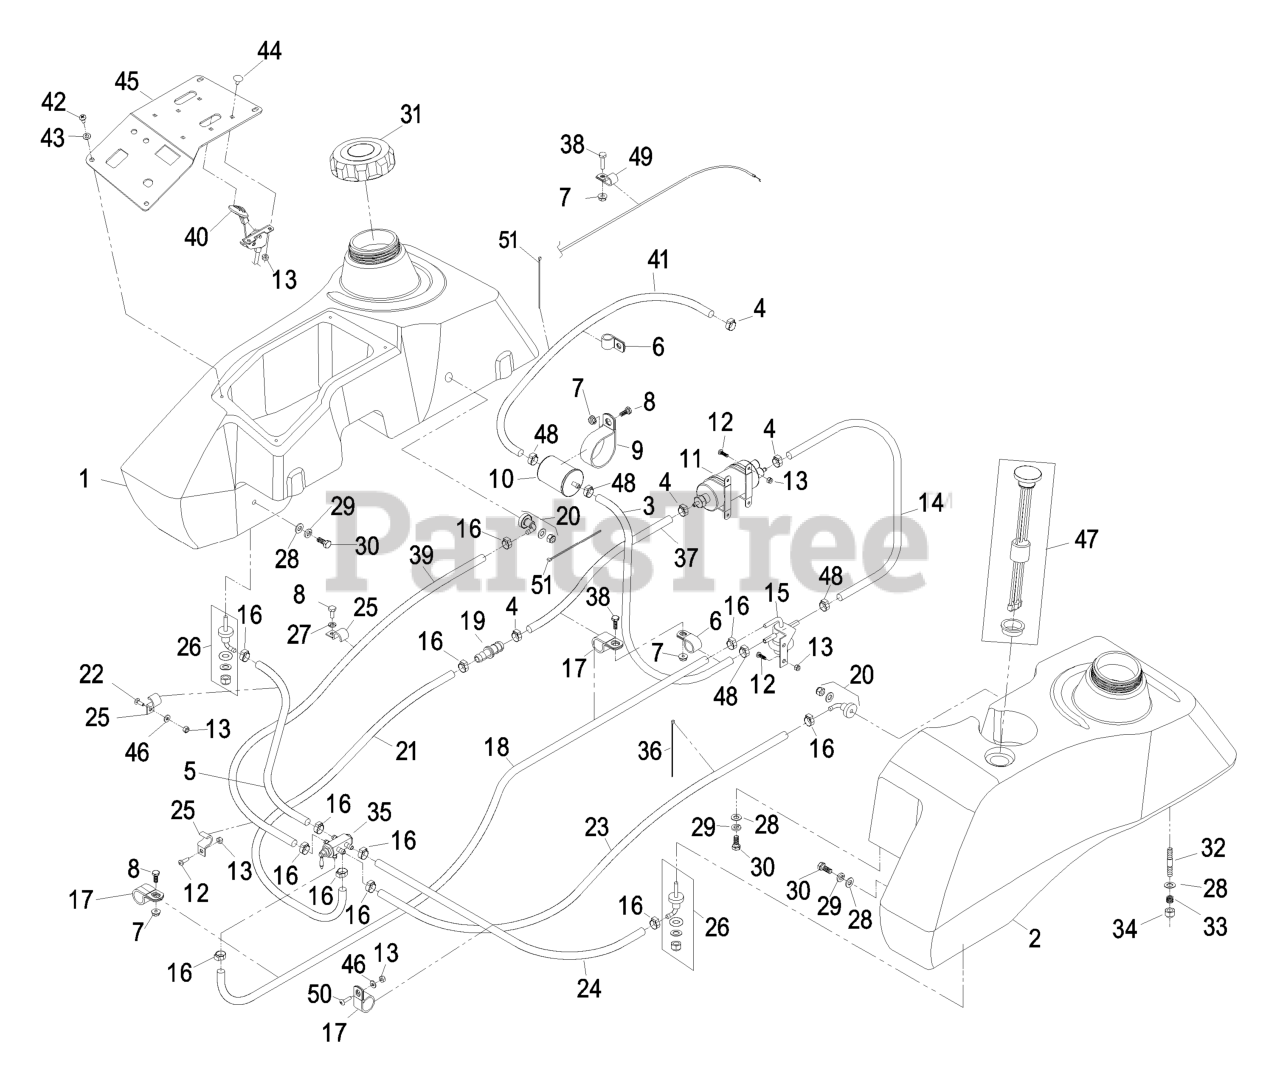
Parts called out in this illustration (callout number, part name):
3	Kit, Fuel Line W/Clamps
4	CLAMP-HOSE, FUEL
5	HOSE-FUEL
6	CLIP-LOOM
8	SCREW-HH
9	CLIP-LOOM
10	Kohler Part No. 24 050 03 Fuel Filter (Large)
11	Kohler Part No. 393 20 Fuel Pump
12	SCREW-PPH
13	NUT-LOCK, NI
14	KIT,FUEL LINE EFI PUMP-RE
15	Kohler Part No. 24 403 17 Fuel Regulator
16	CLAMP-HOSE, FUEL
17	CLIP-LOOM
18	HOSE-FUEL
19	CONNECTOR
20	FITTING-FUEL, BULKHEAD
21	HOSE-FUEL
22	BOLT-CARR
23	HOSE-FUEL
24	HOSE-FUEL
25	CLIP-HALF, LOOM
26	FITTING-FUEL, BULKHEAD
27	WASHER-LOCK
28	WASHER-PLAIN
29	WASHER-LOCK
30	SCREW-HH
31	CAP-FUEL, GAS
32	STUD
33	SPRING-TANK, FUEL
34	NUT-LOCK, NI
35	VALVE-FUEL, DUAL FLOW
36	TIE-CABLE
37	HOSE-FUEL
38	SCREW-HH
39	HOSE-FUEL
40	CONTROL-THROTTLE
41	Kit, Fuel Line W/Clamps
42	SCREW-PTH
43	WASHER-SPRING
44	BOLT-CARR
45	PANEL,CONTROL W/DECALS
46	WASHER-FLAT
47	Kit, Gauge Fuel
48	CLAMP
49	CLIP-LOOM
50	SCREW-HEAD, TRUSS
51	TIE-PLASTIC
